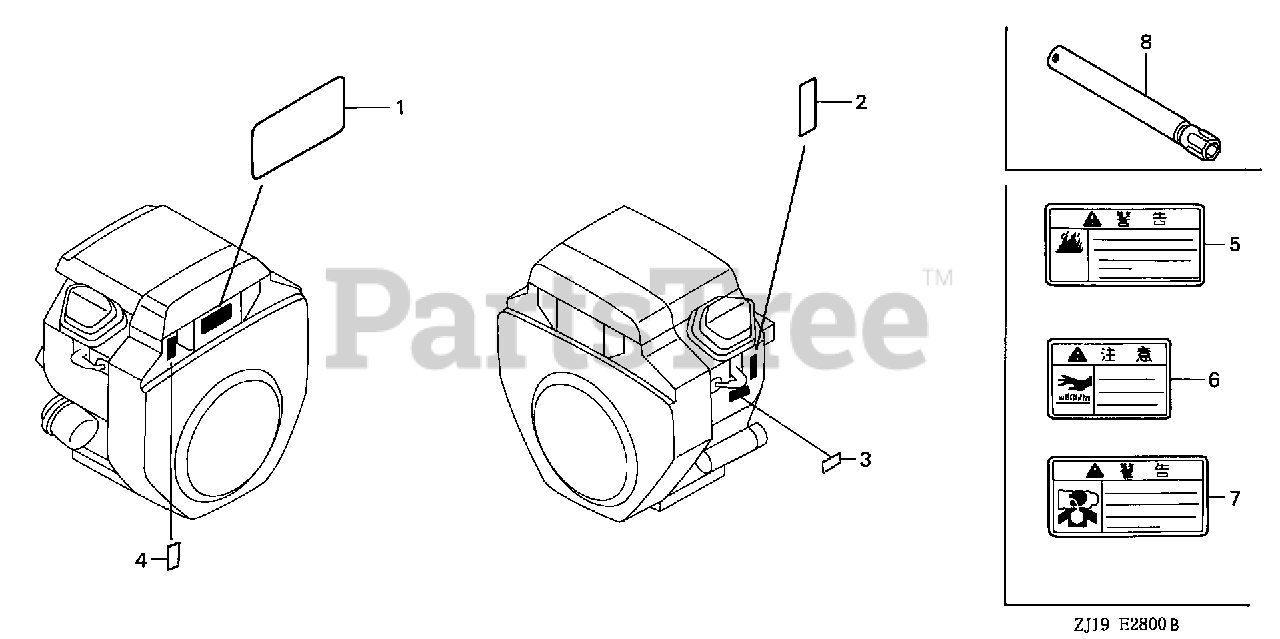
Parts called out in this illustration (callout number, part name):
1	MARK, EMBLEM
2	LABEL, SPECIFICATION (GX620)
3	MARK, OIL ALERT (E)
8	WRENCH COMP., SPARK PLUG
